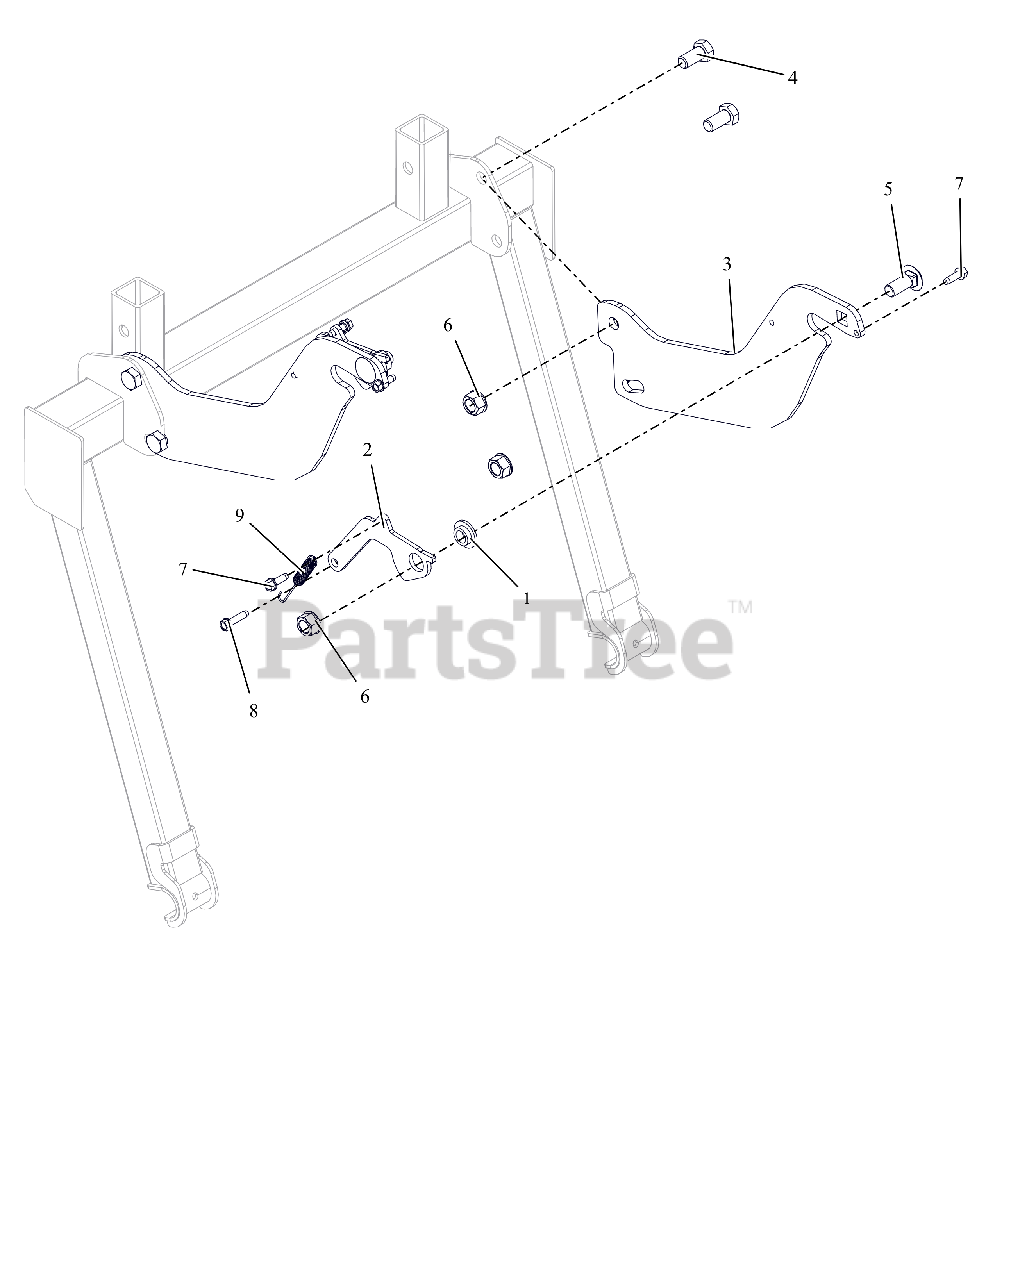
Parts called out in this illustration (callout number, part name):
1	BSHG-FLG .515X.750X.395X1.120
2	BAGGER, LATCH - BLACK
3	LATCH, BAGGER MTG ARMS
4	@BLT-HEX .50-13X1.00 GR5 YWZC
5	@BLT-RDHDSQNK .50-13X1.25 G5YZ
6	@NUT-LK-TOP-FLG .50-13 YWZC
7	SCR-TAP-PM .25-20X.75 TR YWZ
8	@SCR-TAP .25-20X1.00 HWH TR YZ
9	SG-TENS .043X.44X3.31 WLD 5.8
